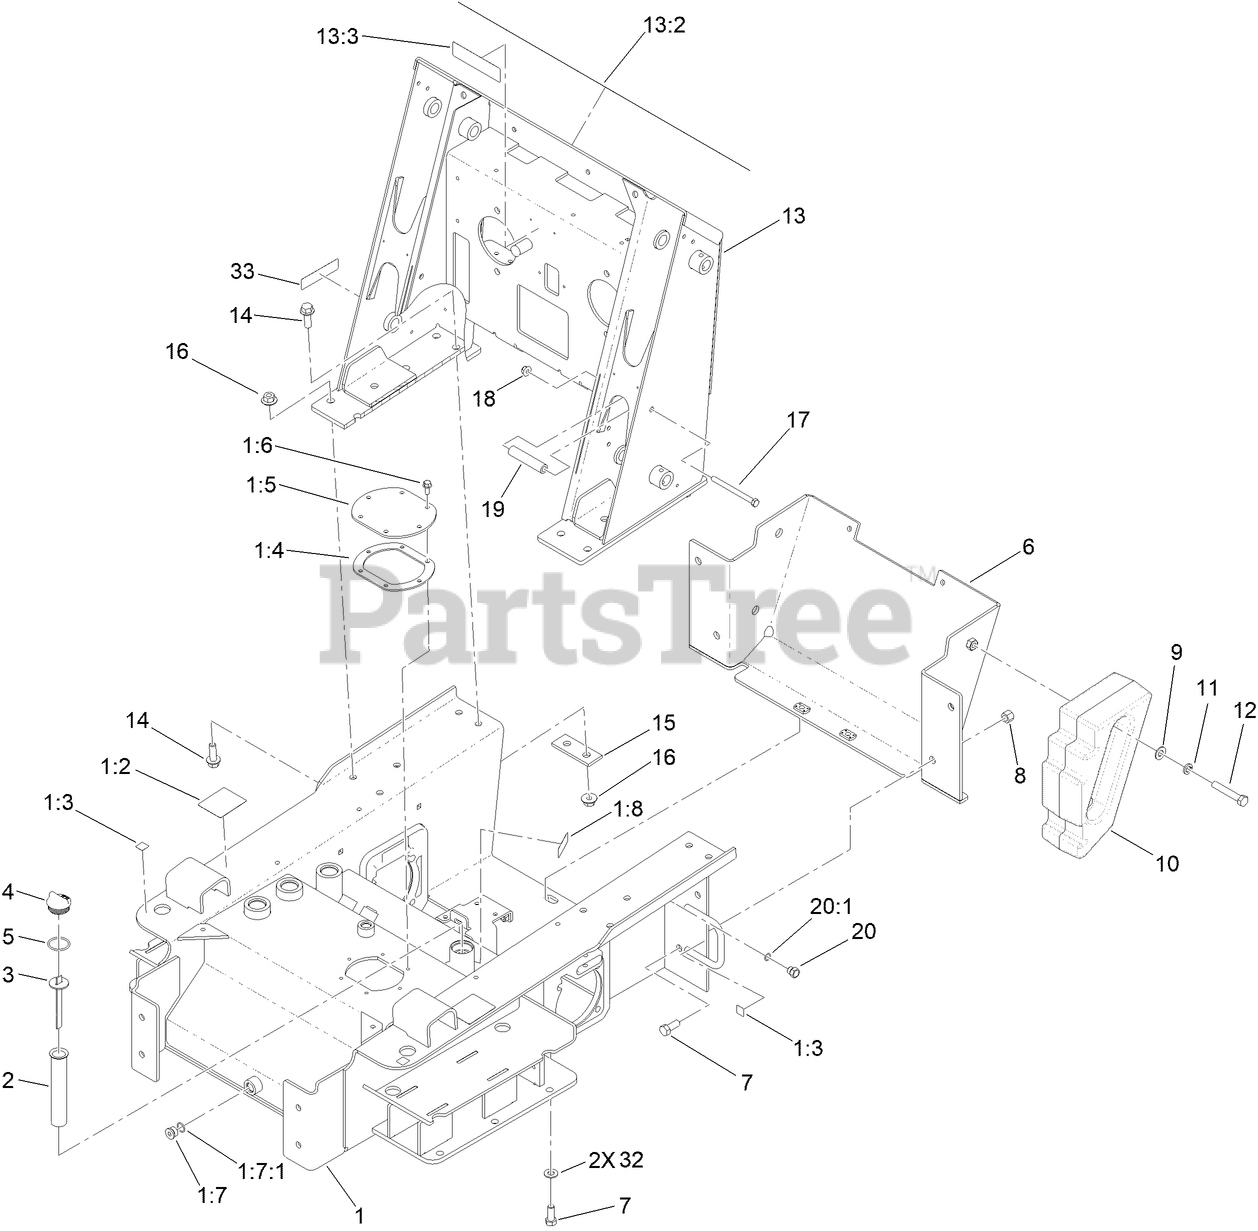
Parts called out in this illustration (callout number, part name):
1	CHASSIS ASM
1:2	DECAL-WARNING
1:3	DECAL-POINT, LIFT
1:4	GASKET-COVER, ACCESS
1:5	COVER-TANK
1:6	SCREW-HHF
1:7	PLUG-HEX
1:7:1	O-RING
1:8	DECAL-OIL, HYD
2	FILTER-SCREEN
3	DIPSTICK-OIL
4	PLUG-PLASTIC
5	O-RING
6	COVER-REAR
7	SCREW-HH
8	NUT-LOCK, NI
9	WASHER-FLAT
10	COUNTERWEIGHT-REAR
11	WASHER-LOCK
12	SCREW-HH
13	LOADER TOWER ASM
13:2	DECAL-PANEL, CONTROL
13:3	DECAL-DANGER
14	SCREW-HHF
15	PLATE-STIFFENER
16	NUT-LOCK, FLANGE
17	SCREW-HH
18	NUT-HF, NI
19	TUBE-SPACER
20	PLUG-HH
20:1	O-RING
32	WASHER-FLAT
33	DECAL-ARRESTOR, SPARK
